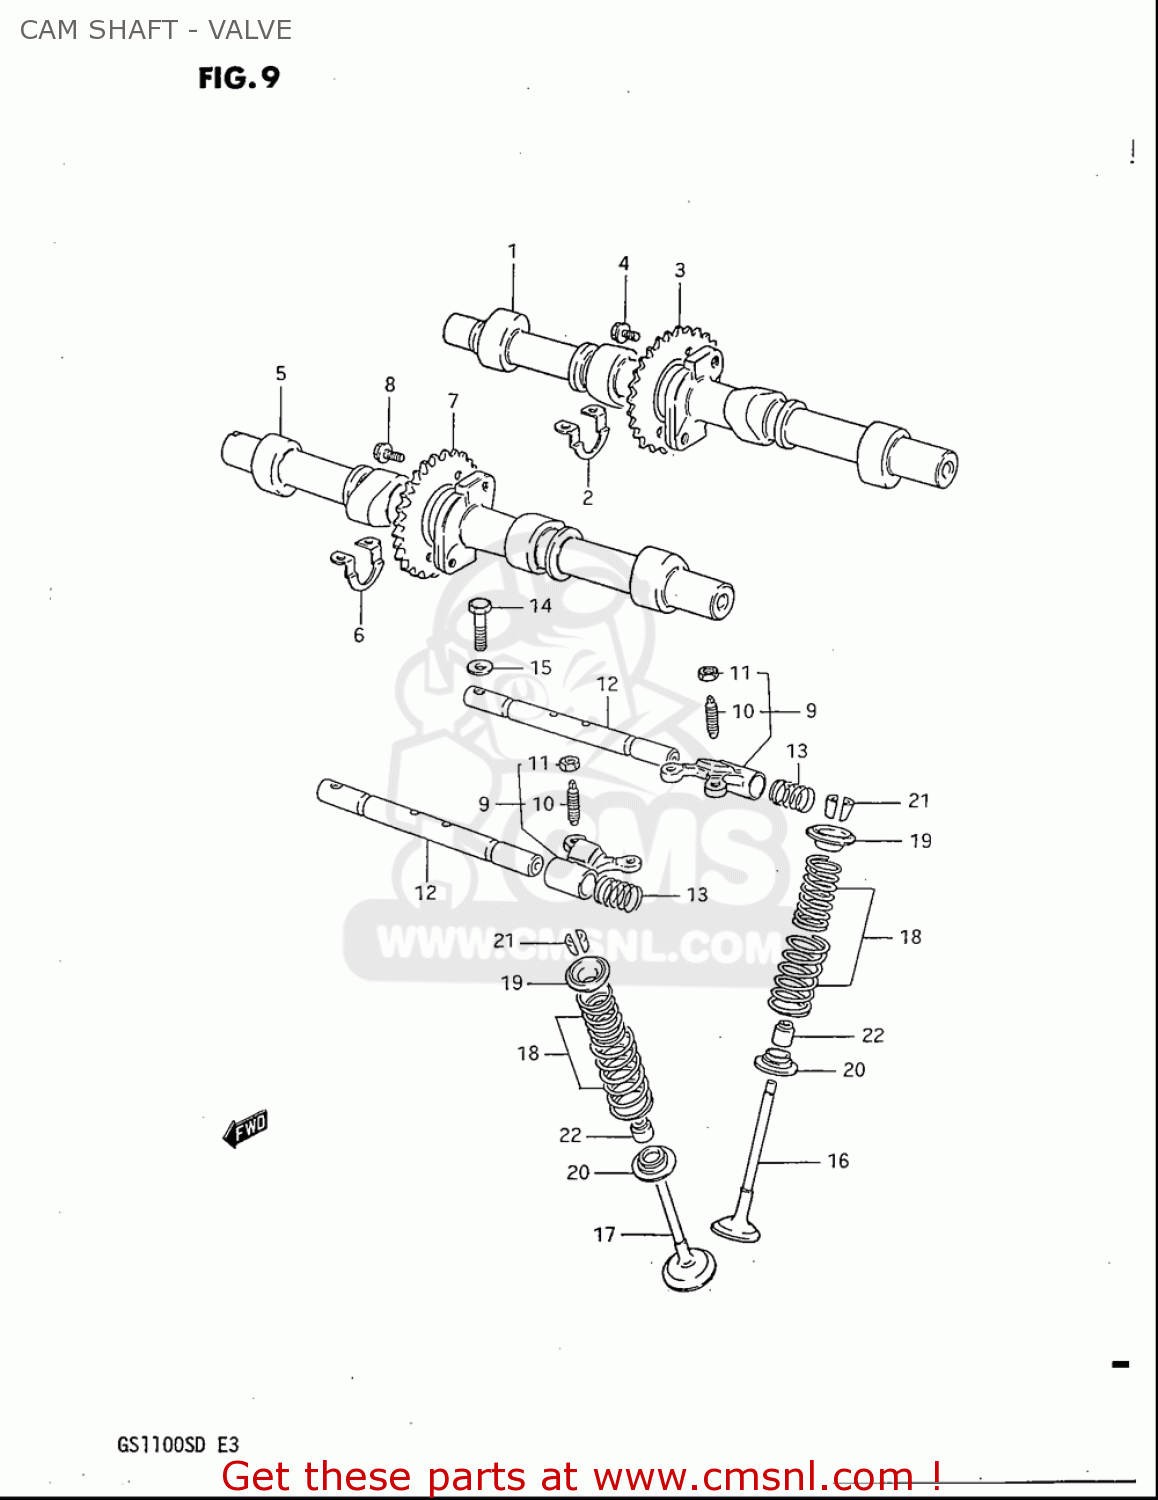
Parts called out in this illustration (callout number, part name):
1	CAMSHAFT SET,INTAKE
2	SHIM,CAMSHAFT
3	SPROCKET,INTAKE CAMSHAFT
4	BOLT(7X11)
5	CAMSHAFT SET,EXHAUST
6	SHIM,CAMSHAFT
7	SPROCKET,EXHAUST CAMSHAFT
8	BOLT(7X11)
9	ARM,VALVE ROCKER
10	SCREW,TAPPET ADJUSTING
11	NUT,TAPPET ADJUSTING
12	SHAFT,VALVE ROCKER
13	SPRING
14	BOLT
15	WASHER
16	VALVE,INTAKE
17	VALVE,EXHAUST
18	SPRING SET,VALVE
19	RETAINER,VALVE SPRING
20	SEAT,VALVE SPRING
21	COTTER VALVE
22	SEAL,OIL(5.5X11X8.2)
